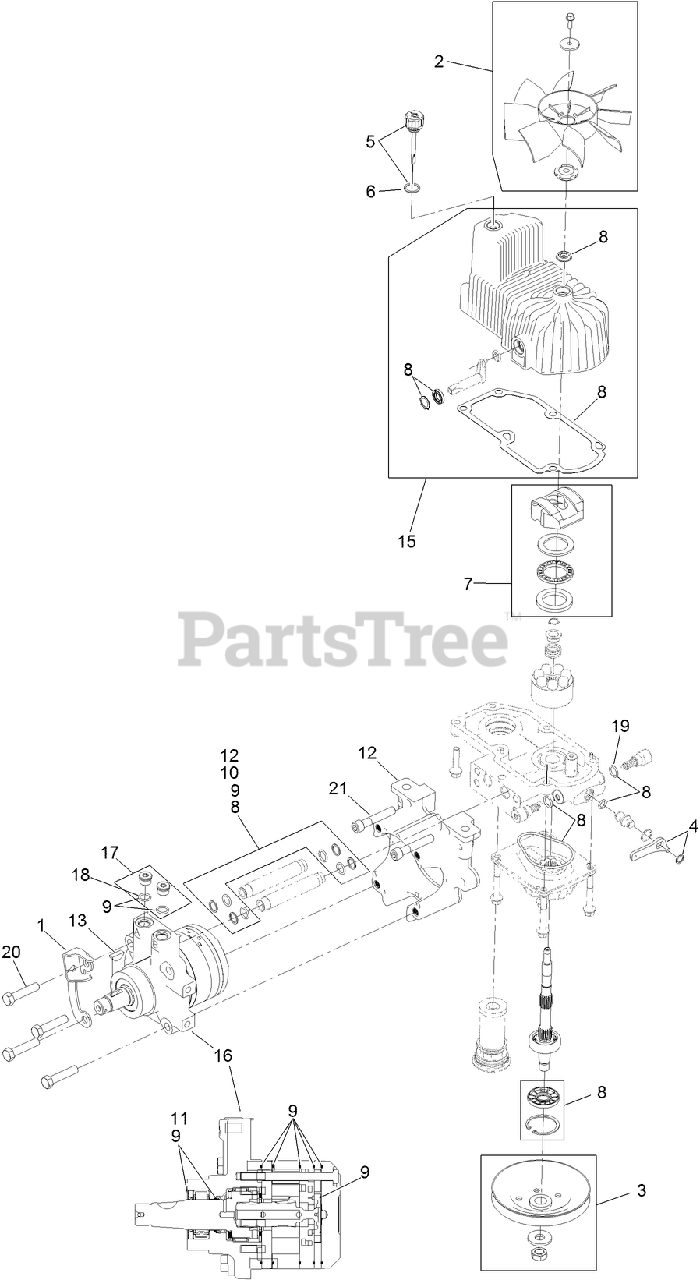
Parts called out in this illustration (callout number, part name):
1	BRACKET-ANCHOR, CABLE
2	FAN KIT
3	PULLEY KIT
4	HANDLE-BYPASS VALVE, HYDRO
5	DIPSTICK-HYDRO W/GASKET
6	GASKET-DIPSTICK, HYDRO
7	SWASH BLOCK KIT
8	PUMP SEAL KIT
9	MOTOR SEAL KIT
10	TUBE SEAL KIT
11	OUTPUT SHAFT SEAL KIT
12	NOSE CUP-UHT
13	KEY-WOODRUFF
15	Housing-LH
16	MOTOR-HYDRAULIC, LH 280CC
17	MAGNETIC PLUGS SERVICE KIT
18	O-RING
19	O-RING-CHECK VALVE
20	SCREW HH
21	SCREW-HSH
